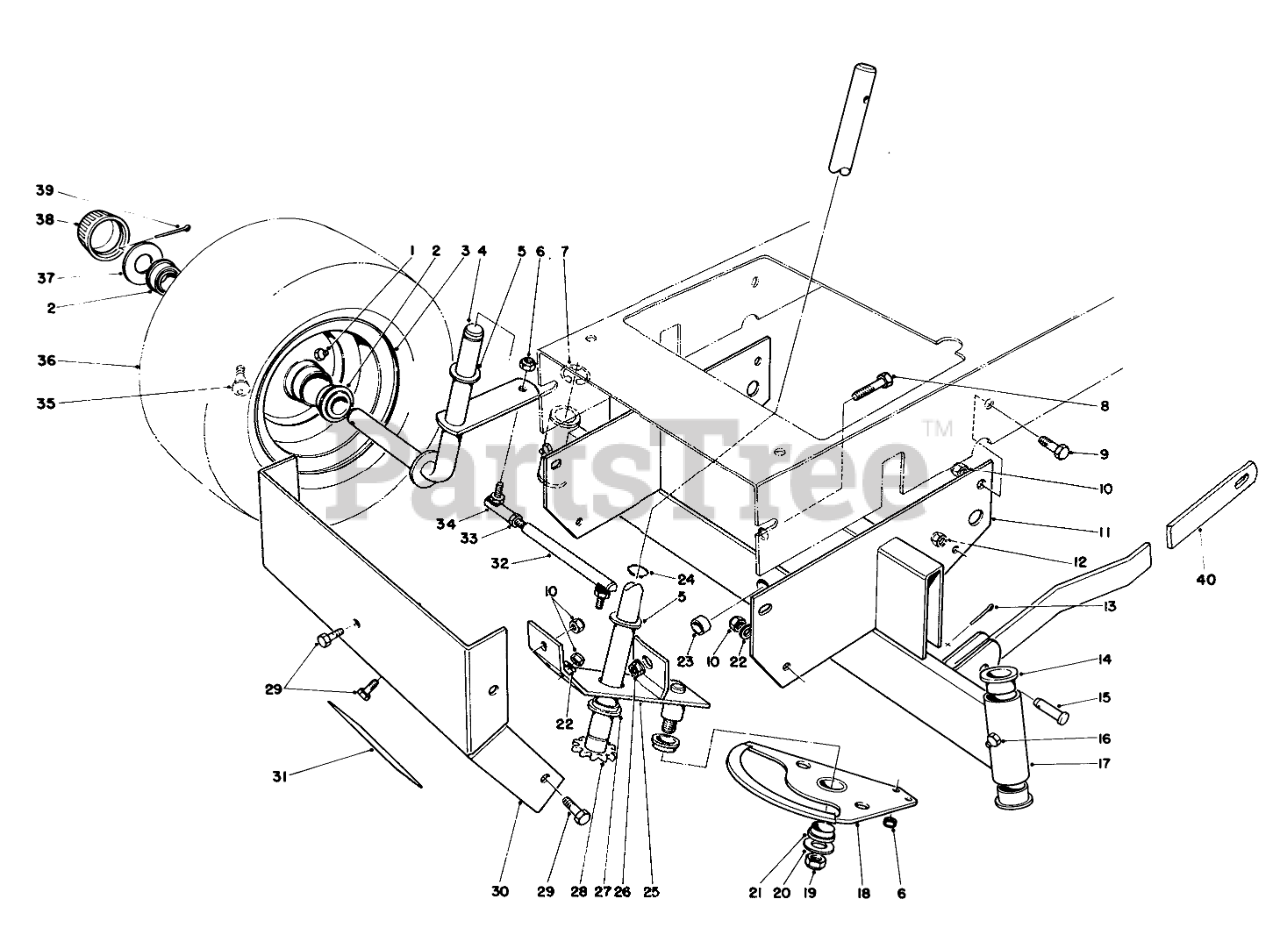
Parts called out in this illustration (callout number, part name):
1	FITTING-GREASE
2	Bearing
4	Spindle-R.H.
5	WASHER-THRUST
6	NUT-LOCK
7	E-RING
8	SCREW-HH
9	SCREW-HH
10	NUT-LOCK, NI
11	Support
12	NUT-LOCK, CONE
13	PIN-COTTER
14	BEARING-FLANGE
15	PIN-CLEVIS
16	GREASE FITTING
17	Axle-Front (Incl. Ref. #14 & 16)
18	Rack-Steering
19	1/2-13 CONELOCK NUT
20	WASHER
21	BEARING-FLANGE
22	WASHER-PLAIN
23	SPACER-AXLE, FRONT
24	RING-RETAINING
25	Rack-Bracket Steering (Incl. Ref. #27)
26	NUT-HF
27	BEARING-FLANGE
28	STEERING SHAFT WA O
29	SCREW-HH
30	Cover-Front
31	Decal-Warning
32	Tie Rod-Steering (Incl. Ref. #32 & 33)
33	NUT-JAM
34	JOINT-BALL
35	STEM-VALVE
36	Tire
37	WASHER-PLAIN
38	Cap-Hub
39	PIN-COTTER
40	Arm-Suspension, Front
